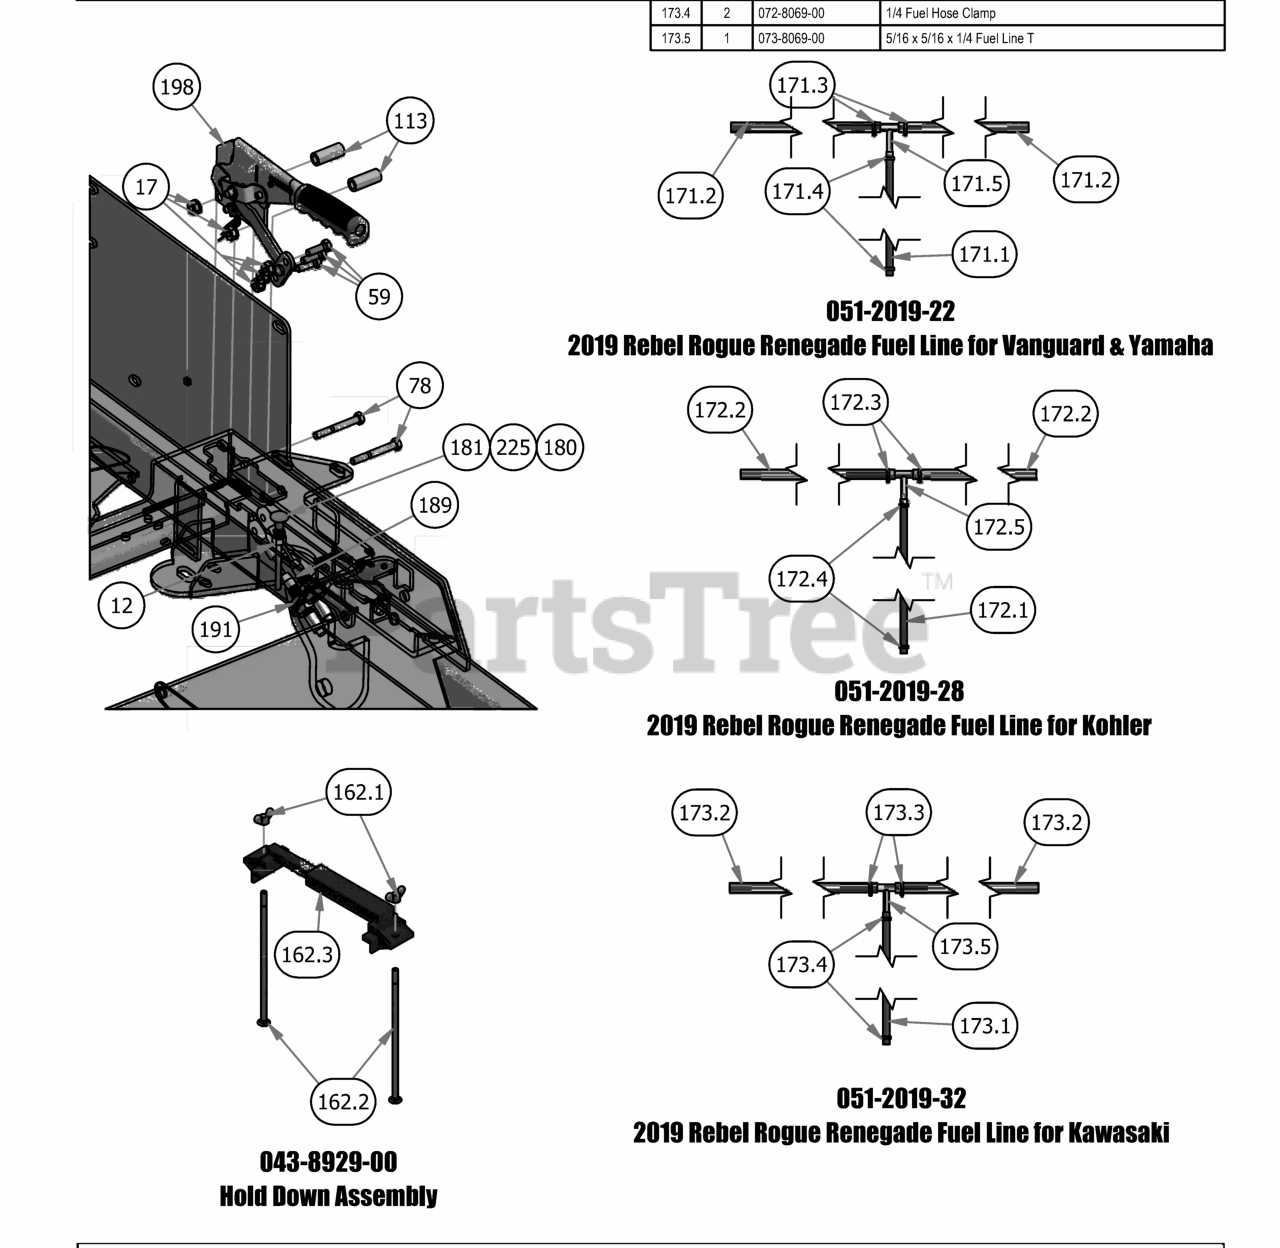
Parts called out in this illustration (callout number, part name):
12	3/8" Fine Threaded Jam Nut
17	5/16-18 Nylon Flange Nut
59	5/16" x 1" Bolt
78	5/16" x 2 1/2" Bolt
113	2019 Outlaw Brake Handle Spacer .625 x 1.5
162.1	1/4" Wing Nut
162.2	1/4-20 X 8 Carriage Bolt
162.3	Battery Hold Down
171.1	1/4" Fuel Line Hose
171.2	5/16" fuel line hose
171.3	5/16 Fuel Line Clamp
171.4	1/4 Fuel Hose Clamp
171.5	5/16 x 5/16 x 1/4 Fuel Line T
172.1	1/4" Fuel Line Hose
172.2	5/16" fuel line hose
172.3	5/16 Fuel Line Clamp
172.4	1/4 Fuel Hose Clamp
172.5	5/16 x 5/16 x 1/4 Fuel Line T
173.1	1/4" Fuel Line Hose
173.2	5/16" fuel line hose
173.3	5/16 Fuel Line Clamp
173.4	1/4 Fuel Hose Clamp
173.5	5/16 x 5/16 x 1/4 Fuel Line T
180	Choke
181	Choke for 36Hp Vanguard & FX1000 Kawasaki
189	2019 Short Brake Cable-Suspension Models
191	2019 Long Brake Cable-Renegade, Rogue
198	2019 Brake Handle Assembly
225	Code Indicator Light
